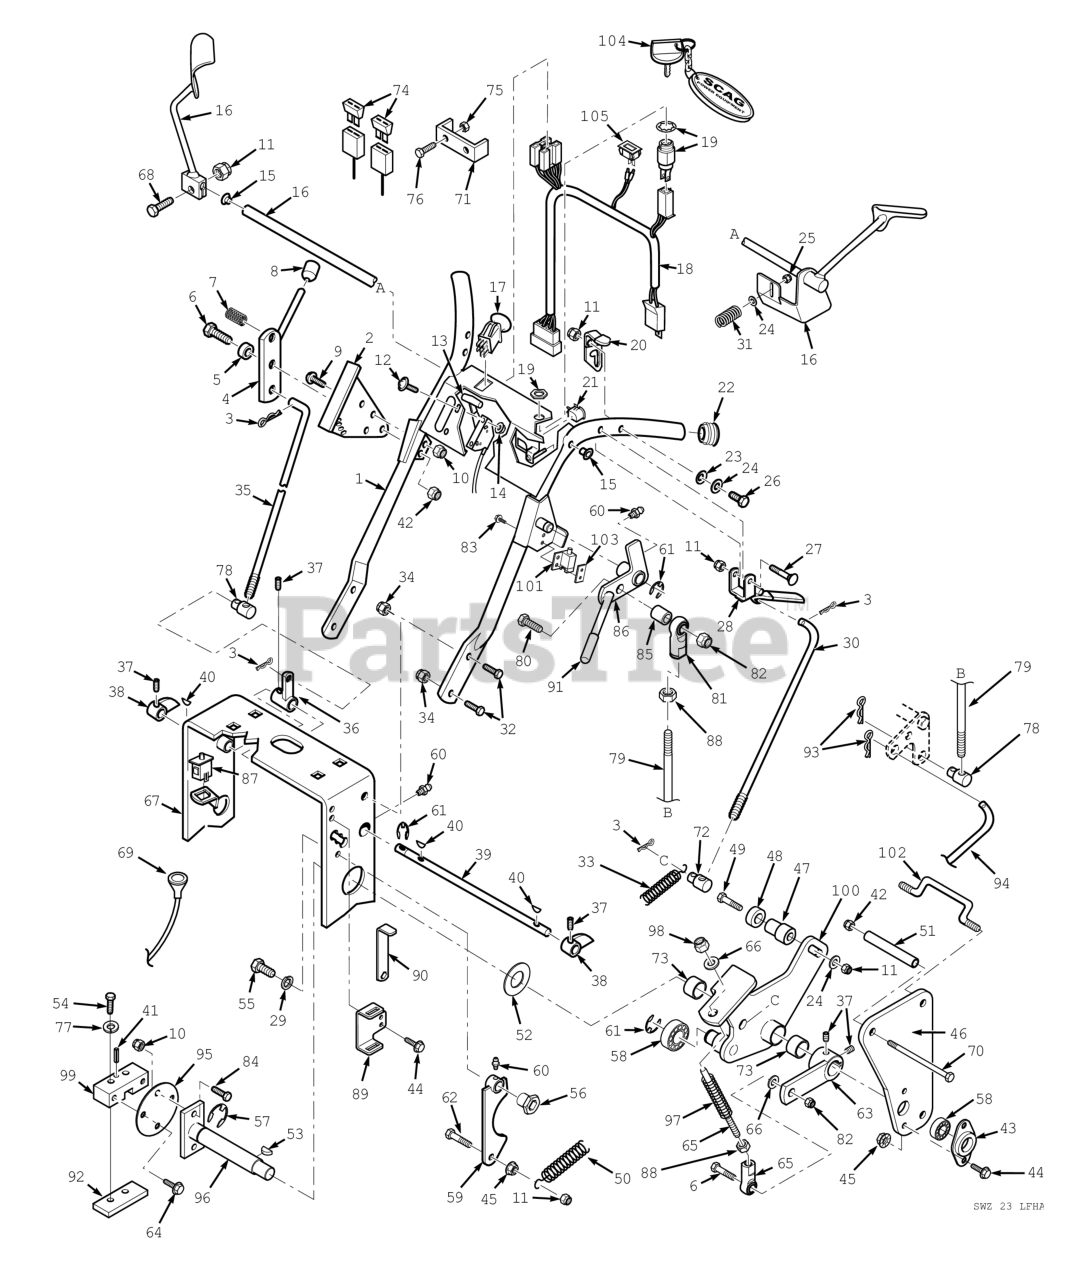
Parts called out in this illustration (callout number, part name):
1	Upper Handle Wlmt. W/Decals
2	QUADRANT, SPEED CONTROL
3	HAIR PIN, .08 DIAMETER X 1-3/16"
4	LEVER, SPEED ADJUSTMENT
5	BUSHING, SPEED ADJUSTMENT LEVER
6	Bolt, Hex Head 3/8-16 x 1-1/2" B&S 32BV
7	BALL PLUNGER
8	KNOB, SPEED ADJUSTMENT LEVER
9	CAPSCREW, 1/4-20 X .75 FLAT HD. HEX SOCKET
10	HEX, NUT, ELASTIC STOP LOCK, 1/4-20
11	HEX NUT, ELASTIC STOP LOCK, 5/16-18
12	Bolt, Carriage #10-24 x 1/2"
13	Throttle Control (15KA & 17KA)
14	Nut, Elastic Stop #10-24
15	Bushing
16	Operator Presence Lever, RH
17	Switch, PTO - 10 Amp
18	Wire Harness, Electric Start
19	KEY SWITCH(INCLUDES MOUNTING HARDWARE)
20	Neutral Latch-RH 461241 Neutral Latch-LH
21	SWITCH, NEUTRAL INTERLOCK
22	Plug, Handle Bar
23	Socket Head Capscrew #8-32 x 1/2"
24	Flatwasher, 5/16-.375 x .875 x .083 (35BV & 37BV-EFI)
25	HEX NUT, ELASTIC STOP LOCK, 5/16-18
26	Bolt, Hex Head 5/16-18 x 2-1/2" (x3) (35BV & 37BV-EFI)
27	Bolt, Hex Head 5/16-18 x 2-1/2" (35BV & 37BV-EFI)
28	Lever, Steering Control
29	Lockwasher, 3/8" Spring, Kawasaki FX / FT & FT-EFI / B&S 32BV
30	Rod, Steering Control
31	Spring, Operator Presence
32	Capscrew, 3/8-16 x 1.0" Serrated Flange Hex Hd
33	Spring
34	NUT, 3/8-16 SERRATED FLANGE HEX HEAD
35	Rod Speed Control
36	SPEED CONTROL ARM
37	Setscrew, 1/4-28 x .25"
38	CAM, SPEED CONTROL(INCLUDES SETSCREW)
39	JACKSHAFT, SPEED CONTROL(FOR 16" DECK)
40	KEY, 1/8 X 1/2, WOODRUFF # 3
41	Roll Pin, Spring 3/16 x 3/4"
42	HEX NUT, ELASTIC STOP LOCK, 5/16-18
43	FLANGE, JACKSHAFT BEARING
44	Cpscrw, 5/16-18 x 1"Serrated Flange Hex Head
45	Nut, Serrated Flange 5/16-18 (Right Front Engine Mounting, Briggs and Kohler Only)
46	Plate, Side
47	Support, Neutral Support
48	BEARING, SPEED CONTROL BELLCRANK
49	BOLT, HEX HD., 5/16-18 X 1-3/4 FULL THREAD
50	SPRING, IDLER TENSION
51	Spacer, Side Plate
52	Flatwasher, 3/4 (.766 x 1.250 x .060)
53	KEY, WOODRUFF #9, 3/16 X 3/4"
54	SERR. FLG. HEX HEAD CAPSCREW, 5/16-18 X 3/4
55	Bolt, Hex Head, 3/8-16 x 1 Gr. 5
56	B ushing, Brake
57	RETAINING RING, 3/4" EXTERNAL "E"
58	BEARINGS, BALL, NEUTRAL RETURN
59	Cam, Neutral (incl. grease ftng.)
60	Greese Fitting, Straight 1/4 - 28
61	RETAINING RING, 5/8" EXTERNAL "E"
62	Bolt, Heax Head 5/16-18 x 1" (48V / 52V)
63	Lever, Speed Control
64	Bolt, Serrated Flange Hex Head 1/4 x 20 x 3/4"
65	Linkage Assembly
66	Flatwasher, 3/8" Special (.391 x .938 x .105)
67	Engine Deck (16" Wide) with Decals - Small Frame
68	Bolt, 5/16 - 18 x 1 - 1/4" Hex Head
69	Choke Control
70	Bolt, Hex Head 3/8-16 x 4-1/4"
71	BRACKET, FUSE HOLDER
72	Swivel Joint, Steering Rod
73	Bushing, oil lube - 3/4 ID x 1.0
74	FUSE, 20 AMP BLADE TYPE AUTOMOTIVE
75	HEX NUT, ELASTIC STOP LOCK # 10-32
76	Screw, #10-32 x 1.5" Phillips - 21KAE
77	Lockwasher, 1/4� Spring
78	SWIVEL JOINT, SPEED CONTROL ROD
79	Rod, Brake Lever
80	Capscrew, Hex Head 3/8-16 x 2.0"
81	Rod End, 3/8-24 RH Thread Female
82	HEX NUT, ELASTIC STOP LOCK, 3/8-16
83	Screw, Hex-Slotted Washer Head #10 32 x 3/4"
84	BOLT, HEX HEAD, 1/4-20 X 3/4 GR.5
85	Spacer, Idler
86	Parking Brake Lever w/Grip & Grease Fitting
87	Switch, Safety
88	HEX NUT, 3/8-24 R.H. THREAD
89	Mounting Bracket, Wrench
90	Wrench
91	GRIP, PARKING BRAKE
92	CLAMP PLATE, PUMP CONTROL
93	COTTER PIN, HAIR - 0.94 X 1.62
94	Rod, Brake Lower
95	Plate, Coupler
96	Shaft, Pump Control
97	Spring, Tracking Adjustment
98	HEX NUT, ELASTIC STOP LOCK, 3/8-16
99	BLOCK, PUMP CONTROL
100	Control, LH (inc. bush. & decal)
101	Switch, Interlock (see below)
102	Rod, Offset
103	Plate, Threaded
104	Key, Assembly w/Fob
105	Hour Meter, Inductive
